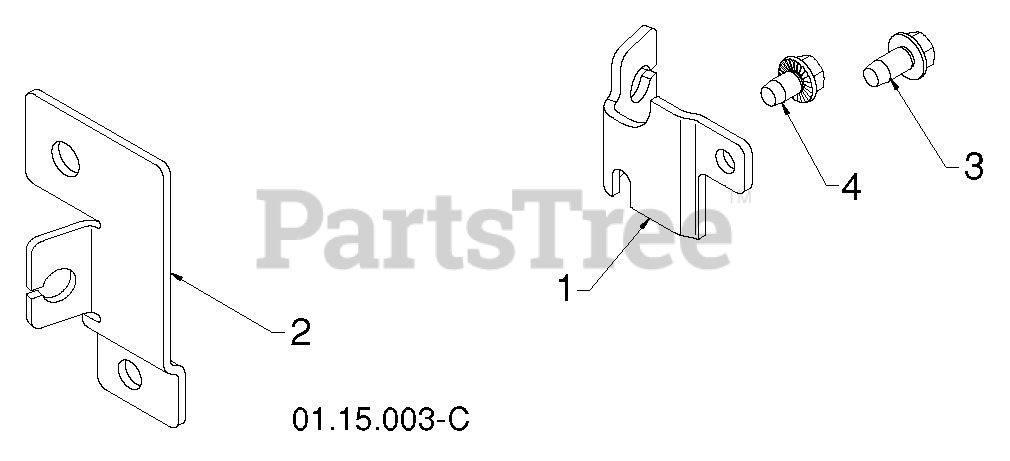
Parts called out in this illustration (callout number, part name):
1	BRACKET.STEER.CABLE.LH
2	BRACKET.STEER.CABLE.RH
3	SCREW
4	SCREW 1/4X20
